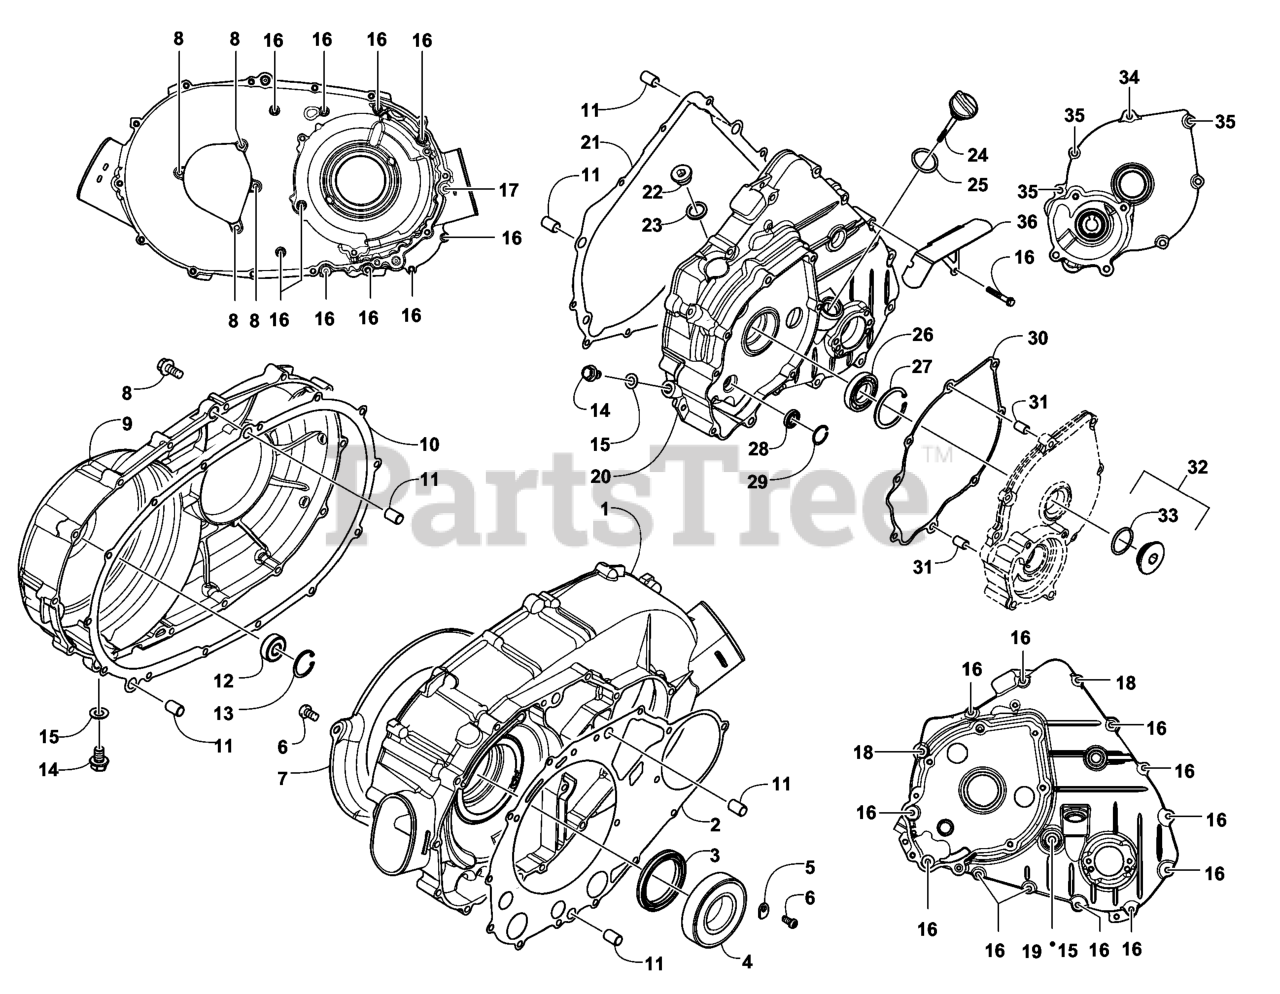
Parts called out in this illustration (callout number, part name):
3	SEAL-CLUTCH HOUSING, RH
4	BEARING-BALL
5	RETAINER-BEARING
6	SCREW-PPH
7	PLATE-AIR INTAKE
8	BOLT-FLANGE
10	GASKET-COVER, V-BELT
11	PIN-DOWEL
12	BEARING-CONRAD
13	CLIP-CIR
14	BOLT-FLANGE
16	BOLT-FLANGE
17	SCREW-HFH
18	BOLT-FLANGE
19	BOLT-FLANGE
21	GASKET-MAGNETO COVER
23	WASHER-CRUSH
24	CASTER/MOUNT ASM
26	BEARING-CONRAD
27	CLIP-CIR
28	BEARING-BALL, RADIAL
29	CLIP-CIR
30	GASKET-COVER, STARTING
31	PIN-DOWEL
32	ARM-ASSIST, 32/36
35	BOLT-FLANGE
36	SHIELD-SHIFT SENSOR
